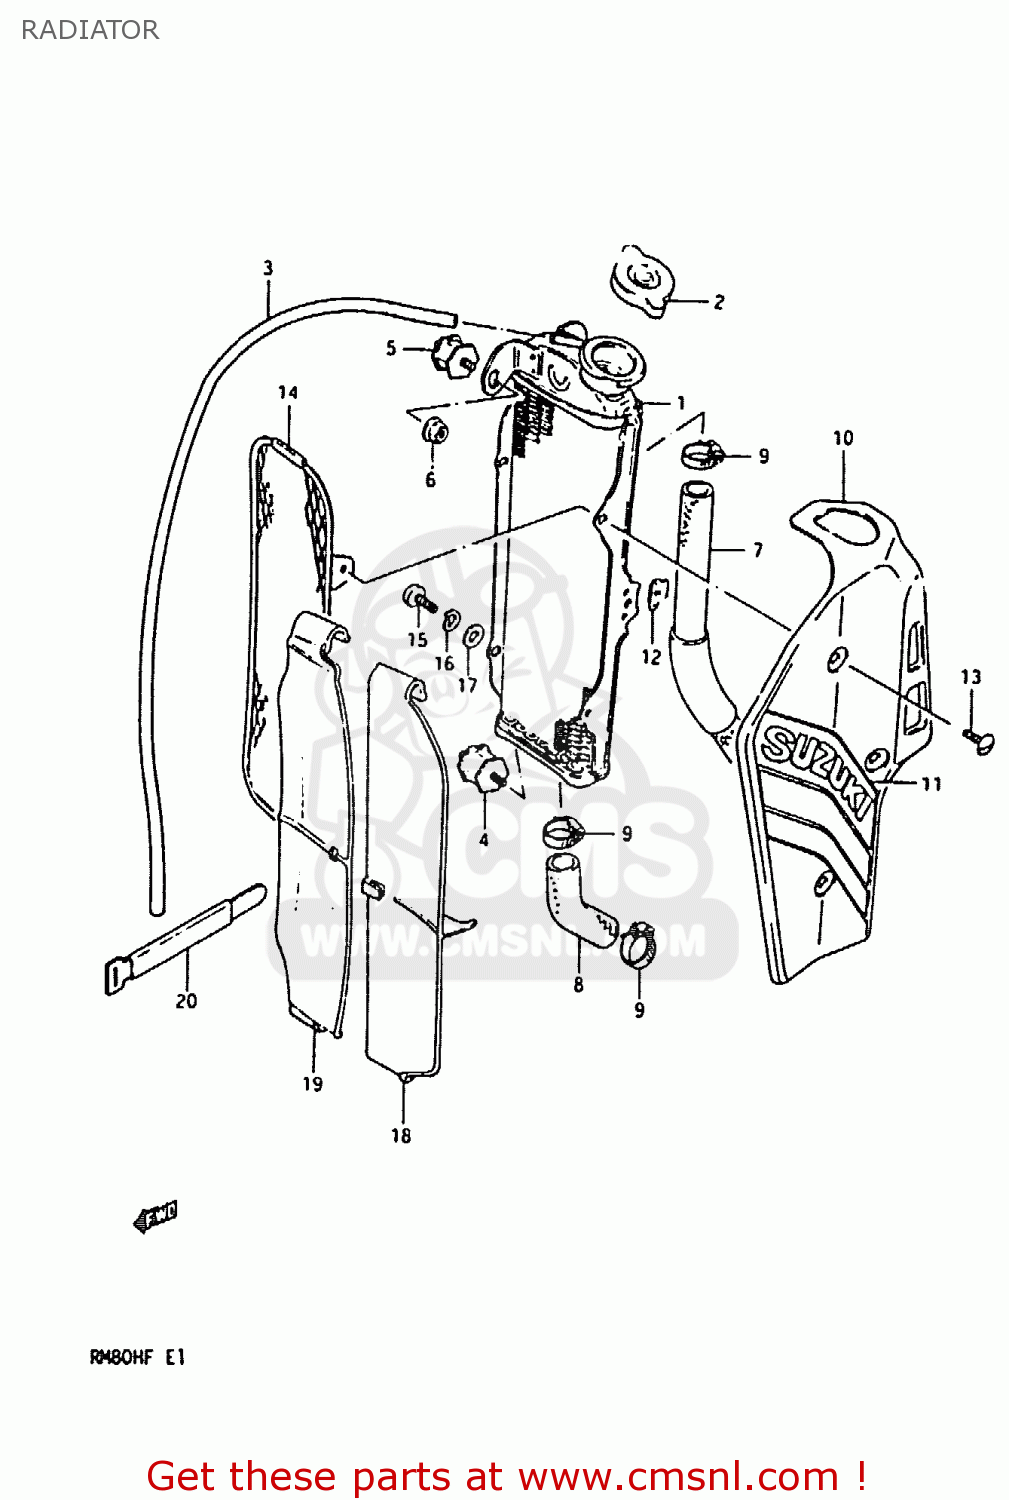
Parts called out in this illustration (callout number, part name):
1	RADIATOR ASSEMBLY,WATER
2	CAP,RADIATOR 1.1
3	HOSE
4	CUSHION,RADIATOR
5	CUSHION
6	NUT 6MM
7	HOSE, INLET
8	HOSE, OUTLET
9	CLAMP
10	COVER,RADIATOR
11	TAPE SET,RADIATOR COVER
12	PLATE,RADIATOR COVER FITING
13	SCREW(6X14)
14	BUMPER,RADIATOR
15	SCREW
16	WASHER,LOCK
17	WASHER
18	LOUVER,RADIATOR
19	LOUVER,RADIATOR
20	CLAMP
